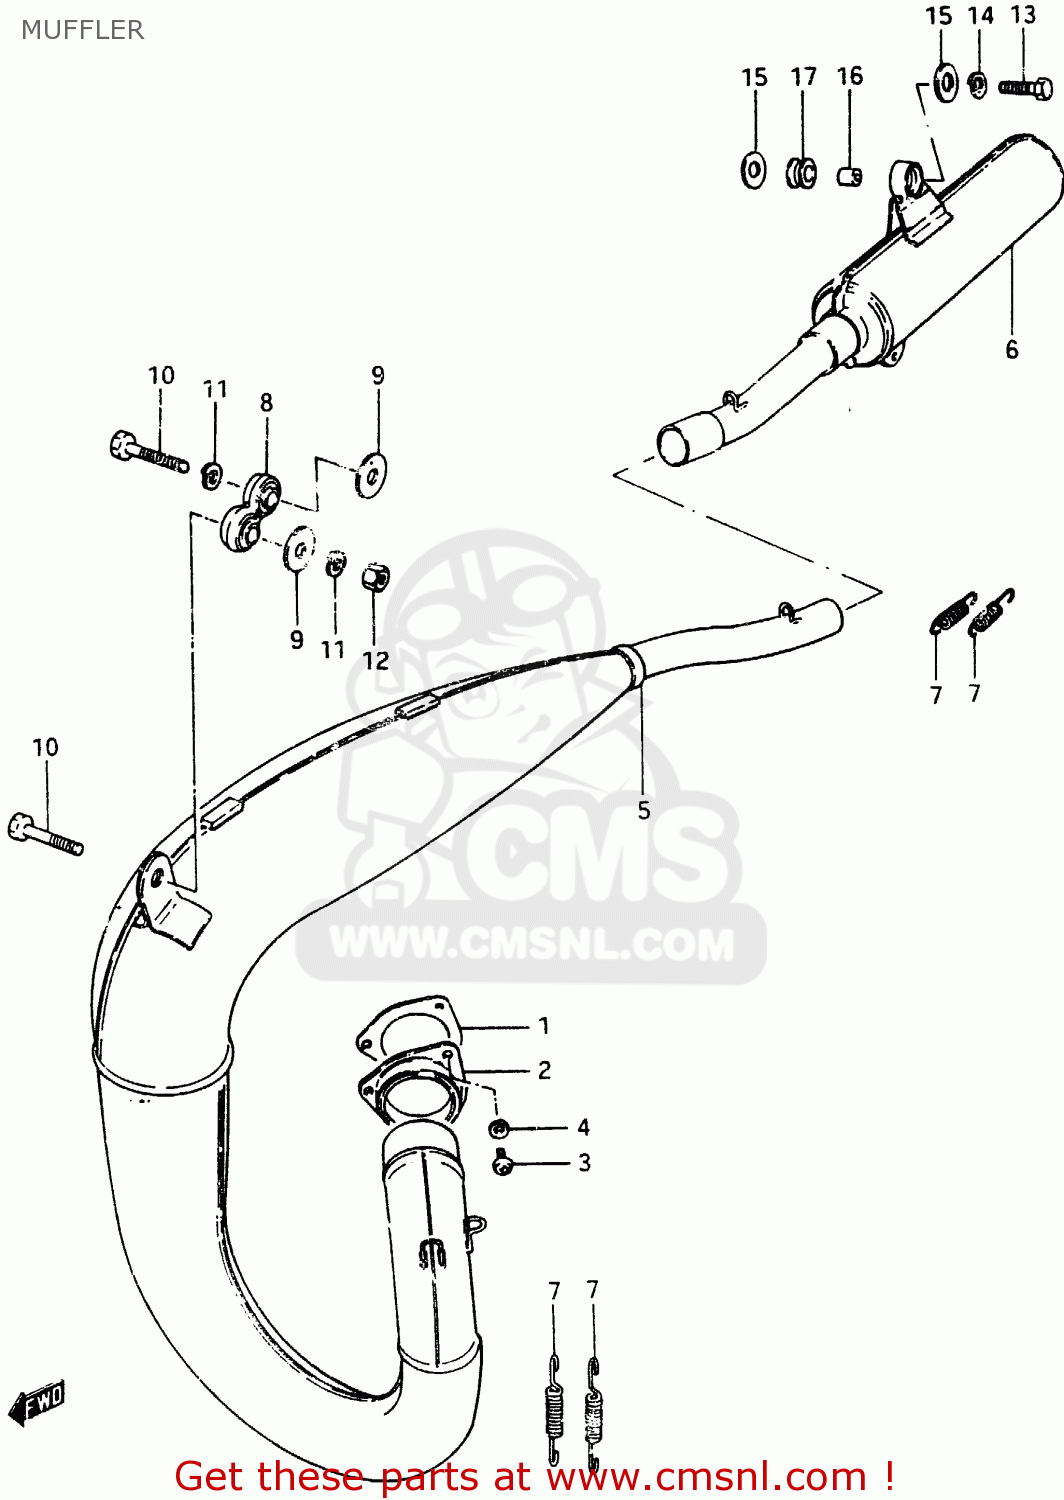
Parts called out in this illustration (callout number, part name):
1	GASKET,EXHAUST PIPE (MCA)
2	FLANGE,EXHAUST PIPE
3	SCREW
4	LOCK WASHER
5	BODY,MUFFLER
6	BODY,MUFFLER
7	SPRING
8	DAMPER,MUFFLER
9	WASHER
10	BOLT(8X32)
11	LOCK WASHER
12	NUT
13	BOLT(8X32)
14	LOCK WASHER
15	WASHER (8.5X29X1.6)
16	SPACER (8.6X12X17.5)
17	CUSHION
